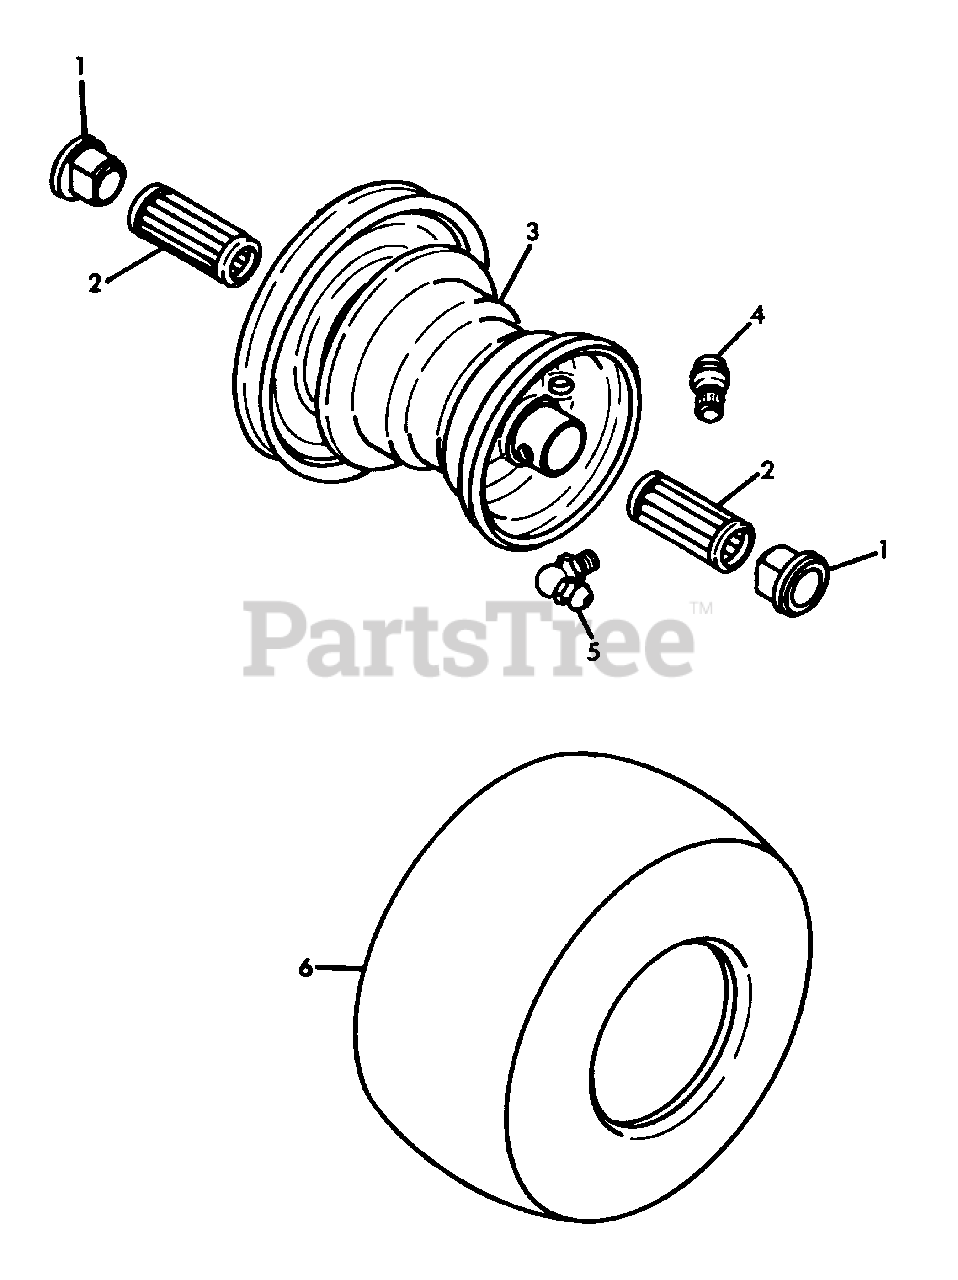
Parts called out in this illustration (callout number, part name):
1	BEARING, FLANGE
2	BEARING, 7/8X2.50
3	RIM
4	ASSEMBLY, VALVE STEM
5	FITTING, LUBE 90 DEG.
6	TIRE, 13X6.50-6
